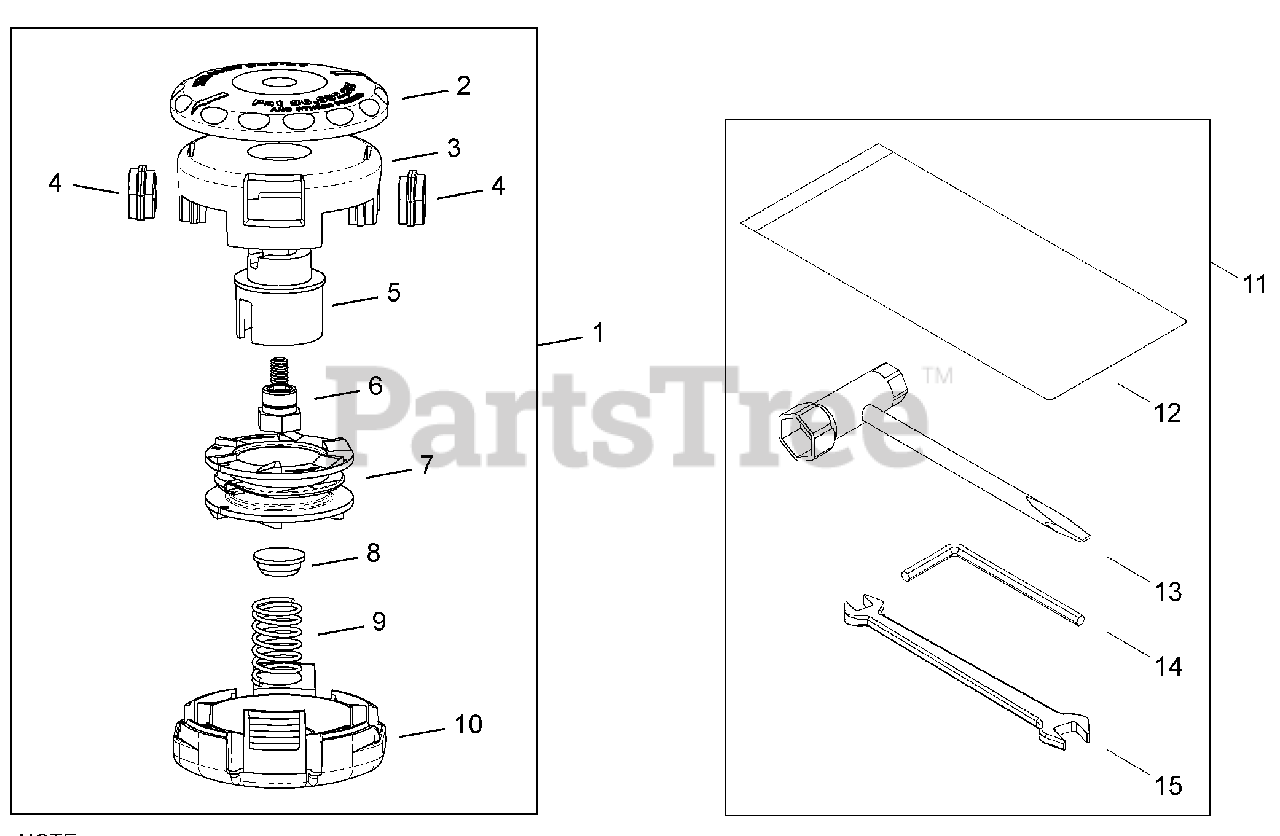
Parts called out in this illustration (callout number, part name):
2	KNOB
3	COVER, SPOOL
4	EYELET
5	CORE
6	BOLT - 7 -- LEFT HAND
7	SPOOL LH
8	CAP
9	SPRING
10	COVER
11	TOOL KIT
12	BAG, TOOL
13	T-WRENCH - 13X19mm
13-1	SPEED-FEED 375 TRIMMER HEAD
14	HEX KEY - 4mm
15	SPANNER - 8X10mm
